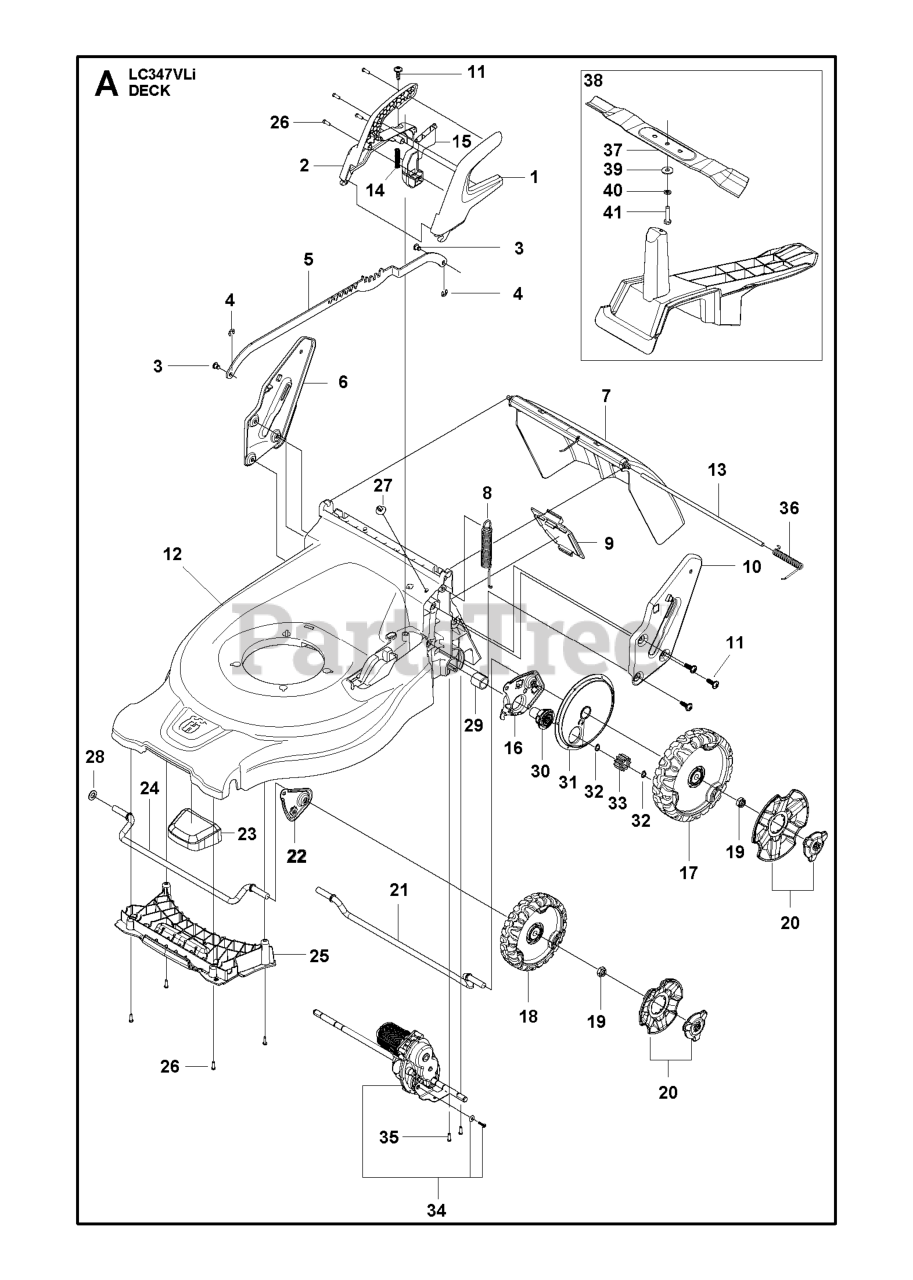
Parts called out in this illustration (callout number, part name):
4	Retaining Ring
20	HUB CAP
26	SCREW ITXPANT T50X16 ZN/FE (A
28	Washers
33	Pinions
35	SCREW ITXPANT T50X16 ZN/FE (A
40	SPRING WASHER
41	SCREW
